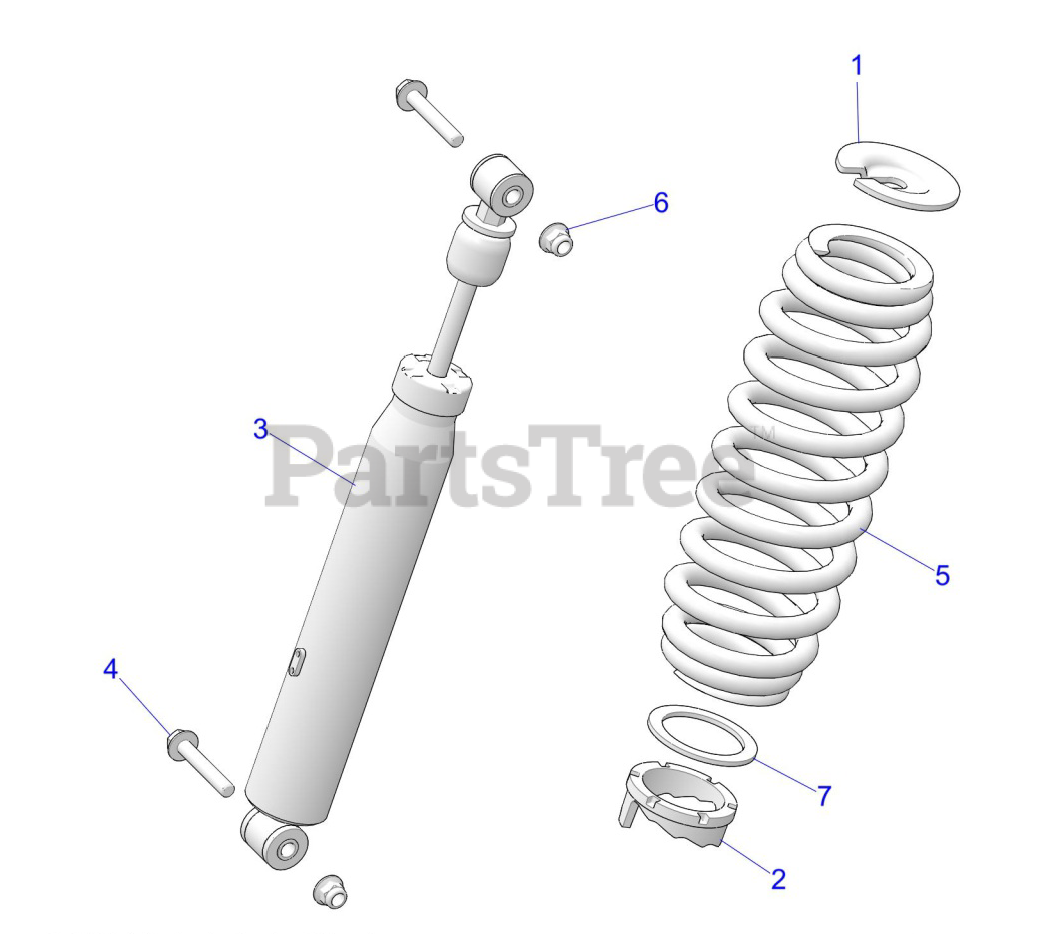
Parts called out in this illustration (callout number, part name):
1	RETAINER-SPRING,STEEL
2	CAM-ADJUSTER,ALUMN,2.30
3	SHOCK-REAR
4	SCR-HXFL-M10X1.25X60 10.9 ZOD
5	SPR-300-500#,14.7FL,2.3ID,BLK
6	NUT-M10X1.25,FLG,NYLOC-OLIVE D
